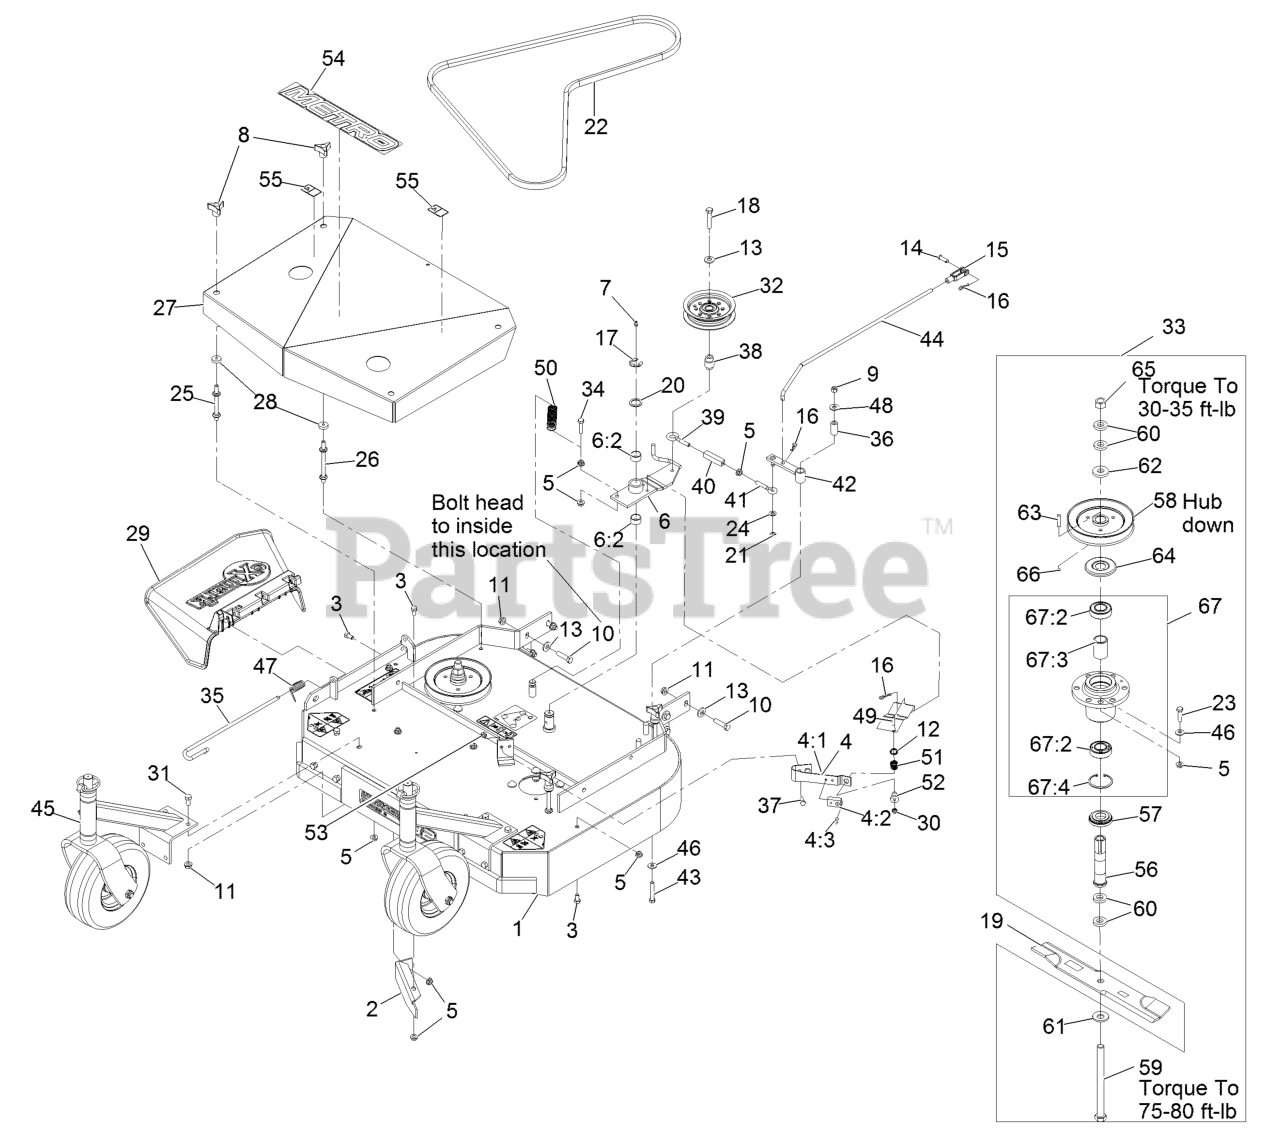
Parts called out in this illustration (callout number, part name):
1	ASM, DECK 32 RIGID
2	BAFFLE-DOGLEG
3	SCREW-HH
4	PAD AND SPRING ASM
6	IDLER ARM ASM
6:2	SLEEVE-BEARING
7	FITTING-GREASE
8	KNOB-3 PRONG
9	NUT-LOCK, NI
10	SCREW-HH
11	NUT-HHF, WHIZ
12	RING-PUSH ON
13	WASHER-BELLEVILLE
14	PIN-CLEVIS
15	YOKE-ADJUSTABLE
16	PIN-COTTER
17	RING-RETAINING, EXT
18	SCREW-HH
20	WASHER-SPINDLE
21	RING-RETAINING, EXT
22	BELT,BLADE METRO 32
23	SCREW-HH
24	WASHER-PLAIN
25	STUD-SHIELD, BELT (SHORT)
26	STUD-SHIELD, BELT (LONG)
27	ASM,SHIELD W/DECALS 32 ME
29	CHUTE DEFLECTOR XRK M056
30	NUT-LOCK, NI
31	SCREW-HH
33	ASM, CUTTER HOUSING OUTER
34	SCREW-HH, SPECIAL
35	PIN-CHUTE
36	TUBE-PIVOT
37	SCREW-HH
38	BUSHING-ENGAGEMENT
39	EYEBOLT-THREAD, LH
40	BODY-TURNBUCKLE
41	EYEBOLT-THREAD, RH
42	ARM-ASSIST, 32/36
43	SCREW-HH
44	ARM-ASSIST, LINKAGE
45	ASM,CASTER/MOUNT
46	WASHER-SPRING
47	SPRING, TORSION
48	WASHER-FLAT
49	ROD-BRAKE
50	SPRING-EXTENSION
51	SPRING-COMPRESSION
52	SPACER-FLANGED
53	NUT-LOCK, NI
54	Decal-Metro
55	DECAL-WARNING
56	TUBE-SPINDLE, SHORT
57	SPACER-GUARD, BOTTOM
58	SHEAVE
59	SCREW-CAP, HH
61	WASHER-SPRING
62	WASHER-RETAINER, SHEAVE
64	GUARD-BEARING, TOP
65	NUT-HEX
66	SETSCREW
67	KIT, CUTTER HOUSING
67	CUTTER HOUSING ASM
67:2	BEARING-JACKSHAFT
67:3	SPACER-BEARING
67:4	RING-SNAP
